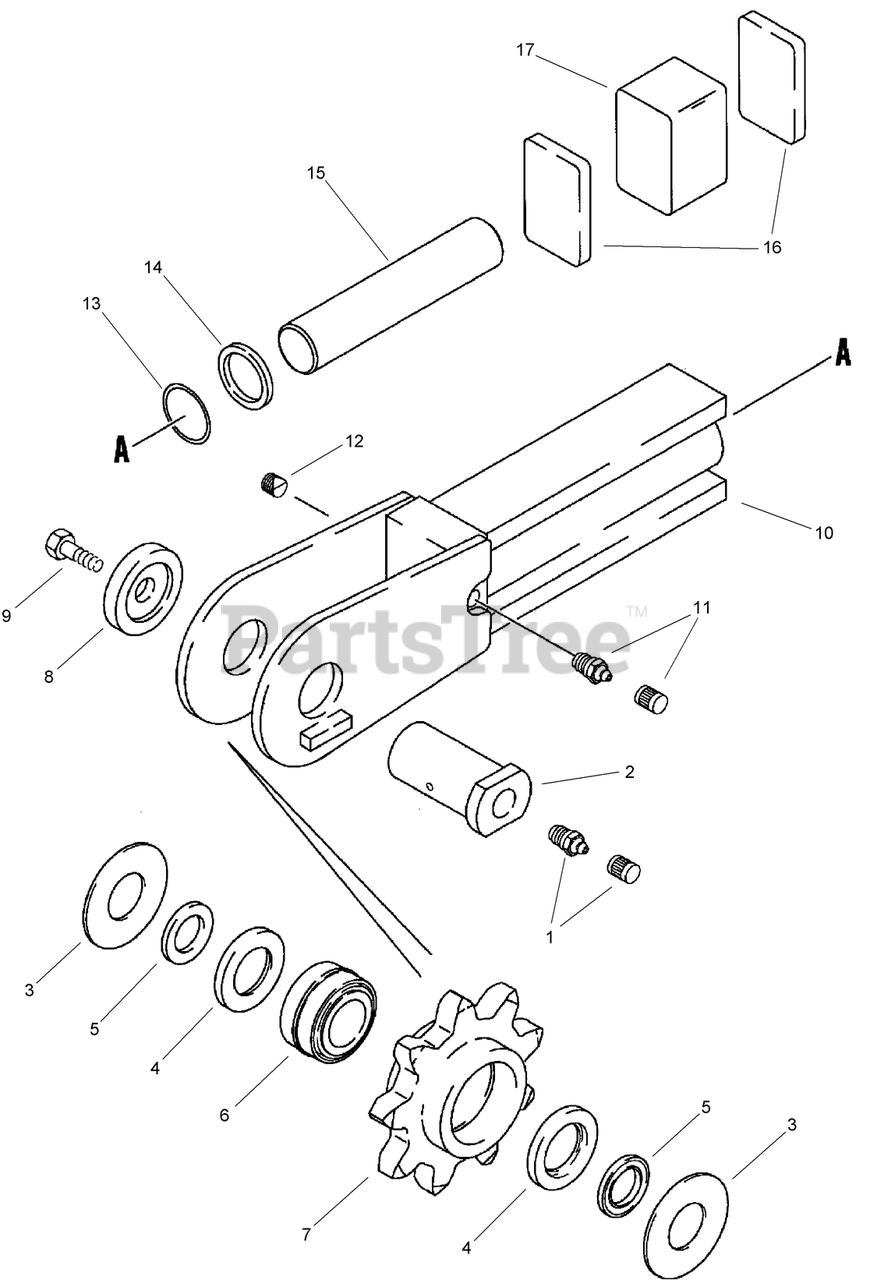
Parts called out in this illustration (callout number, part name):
1	FITTING-LUBE, STRAIGHT
2	PIN-sprocket
3	WASHER-BOOM, END (ROLLER)
4	SEAL-ROLLER
5	SPACER-bearing
6	BEARING KIT
7	SPROCKET-boom end (used with 4 foot boom)
7	SPROCKET-boom end (used with 5 and 6 foot booms)
10	END-boom
11	FITTING-LUBE, STRAIGHT
12	PLUG-BLEED
14	WASHER-BACKUP
15	ROD-BOOM, END (CYLINDER)
16	PLATE-cushion
17	BLOCK-cushion, boom end
